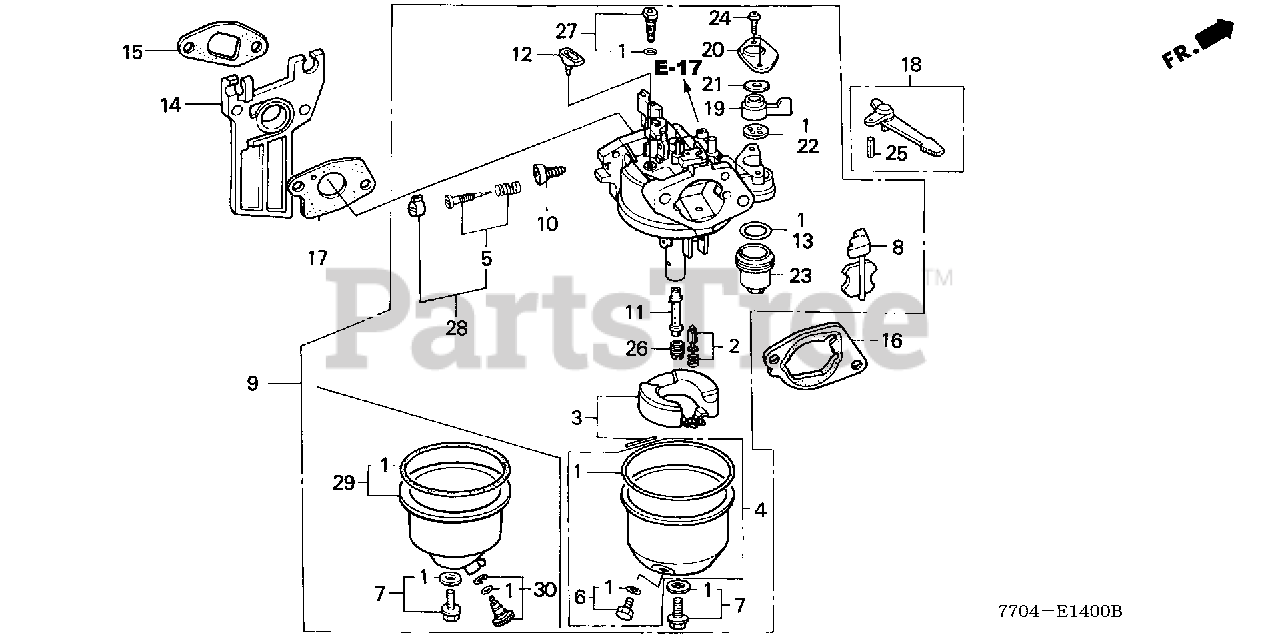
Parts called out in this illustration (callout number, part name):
1	GASKET SET (CARBURETOR NO.)
1	GASKET SET (CARBURETOR NO.) (INCLUDES 16173-001-004)
2	VALVE SET, FLOAT
4	CHAMBER SET, FLOAT (CARBURETOR NO.)
4	CHAMBER SET, FLOAT
5	SCREW SET, PILOT
6	SCREW SET, DRAIN (CARBURETOR NO.)
7	SCREW SET
9	CARBURETOR ASSY. (BE15K B)
9	CARBURETOR ASSY. (BE15K C)
9	CARBURETOR ASSY. (BE15G B)
9	CARBURETOR ASSY. (BE15G C)
10	SCREW, THROTTLE STOP
11	NOZZLE, MAIN
13	GASKET, FUEL STRAINER CUP
14	INSULATOR, CARBURETOR
15	GASKET, INSULATOR
16	SPACER, CARBURETOR
17	GASKET, CARBURETOR
18	LEVER, CHOKE (STD)
19	LEVER, PETCOCK (CARBURETOR NO.)
20	PLATE, LEVER SETTING (CARBURETOR NO.)
21	SPRING, PETCOCK LEVER
22	GASKET, PETCOCK
23	CUP, FUEL STRAINER
24	SCREW, PAN (3X6)
24	SCREW, PAN (3X8) (CARBURETOR NO.)
25	PIN, SPRING (2X12)
26	JET, MAIN (#80) (CARBURETOR NO.)
26	JET, MAIN (#82) (CARBURETOR NO.)
26	JET, MAIN (#85) (CARBURETOR NO.)
27	JET SET, PILOT (#38)
30	SCREW SET, DRAIN (CARBURETOR NO.)
